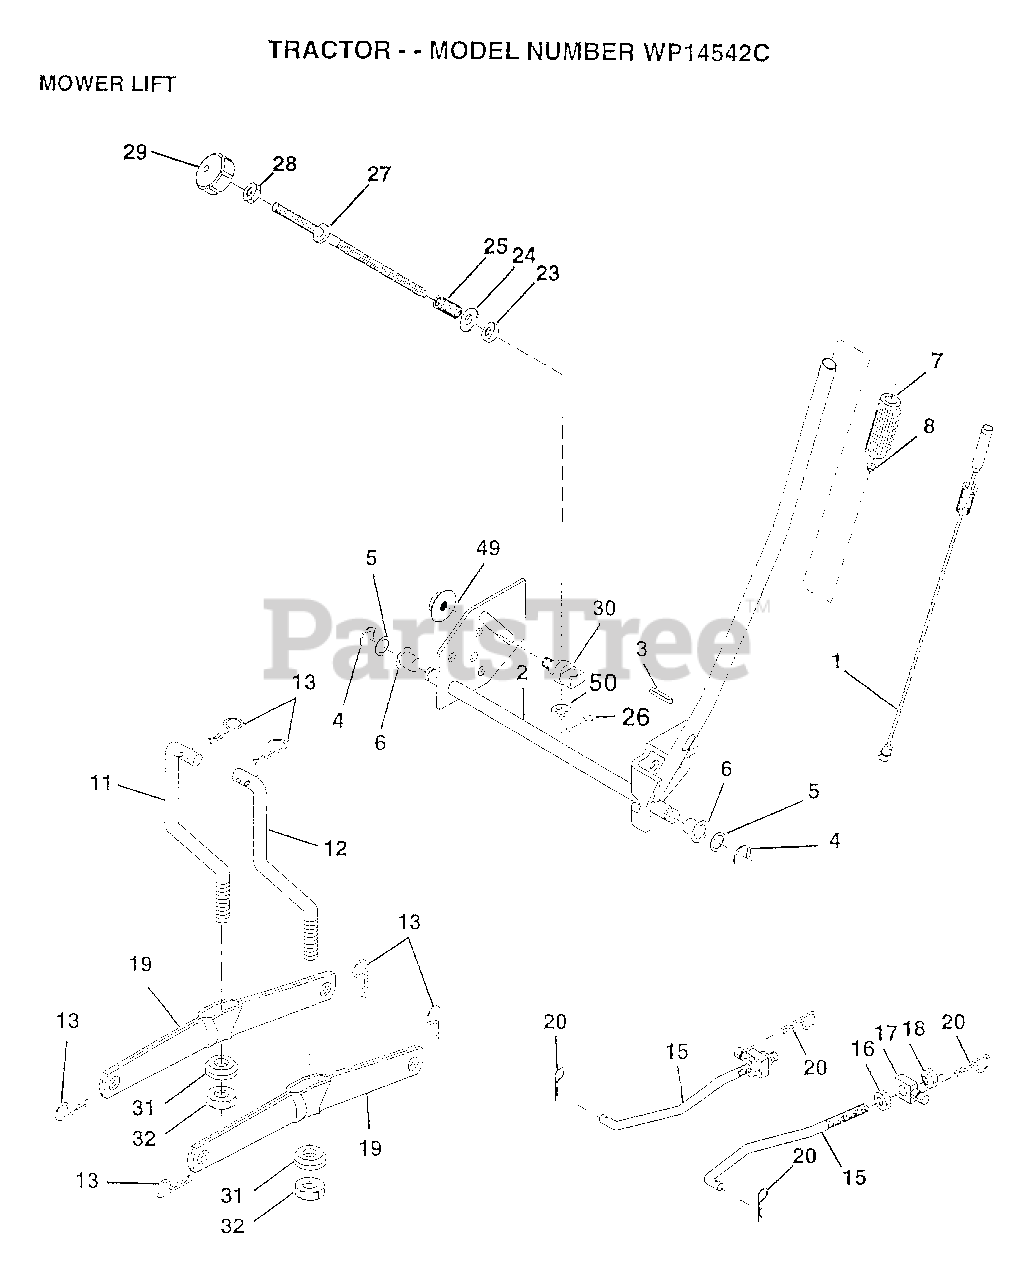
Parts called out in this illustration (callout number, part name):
1	WIRE.ASM.INNER.SP
2	"SHAFT AMS LIFT,RH"
3	PIN GROOVE
5	WASHER
6	NYLON BEARING
7	GRIP
15	LINK.FRONT
16	NUT
17	TRUNION
18	NUT.LK.W/WSH.1/2.
19	ARM SUSP REAR
20	RETAINER.SPRING
23	NUT T
24	WASHER
24	SPRING.COMP.INF.H
27	ROD.ADJ.LIFT
28	NUT
29	KNOB INF 3/8-16
30	TRUNNION
31	BEARING PVT LH
32	NUT.CROWNLOCK.3/8
49	NUT.HXFLG.LOCK.
50	NUT PUSH M
